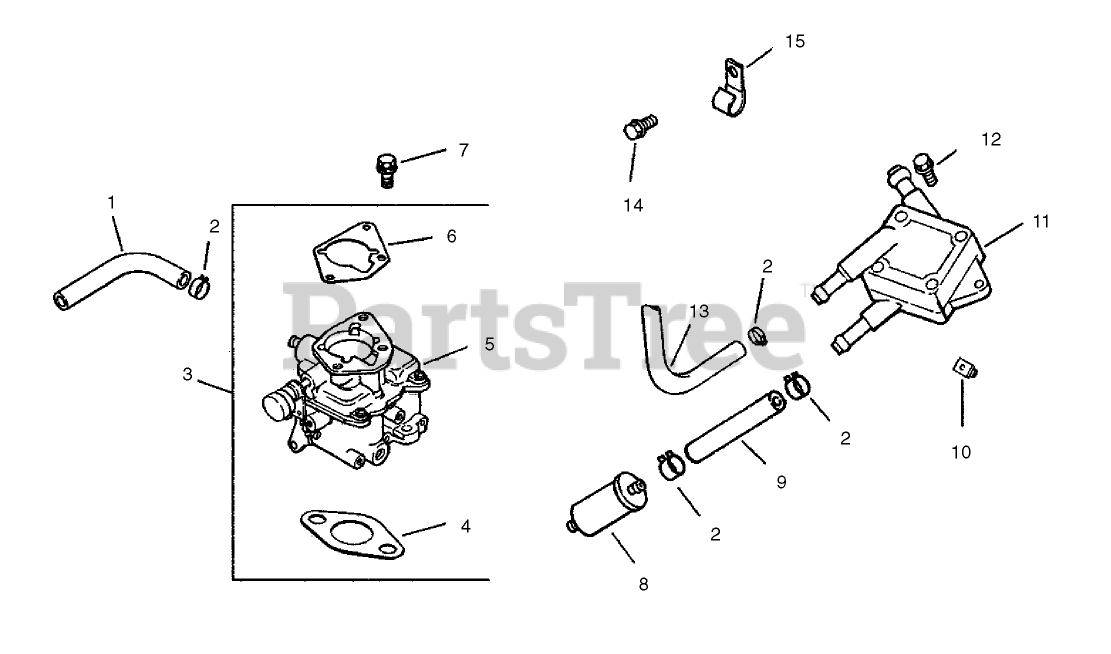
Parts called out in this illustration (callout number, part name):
1	Line-Fuel (9.5)
2	CLAMP-HOSE, SPRING (1/2)
3	Kit, carburetor with gasket (Includes 4-6)
4	Gasket-Carburetor
5	Carburetor asm. (For information only not available separately)(Service with: 24 757 01-S, 24 757 02-S,24 757 03-S, 24 757 07-S, 24 757 08-S24 757 09-S)
6	GASKET-BASE, AIR CLEANER
7	SCREW-FLANGE (M6X1.0X30)
8	Filter-Fuel
9	Line-Fuel (3.5)
10	Nut-Plastic
11	PUMP-FUEL
12	SCREW-TAP (M6X1.7X18)
13	Line-Fuel, Flexible (15.5)
14	Screw-HF (M6x1.0x12)
15	CLIP-CABLE
